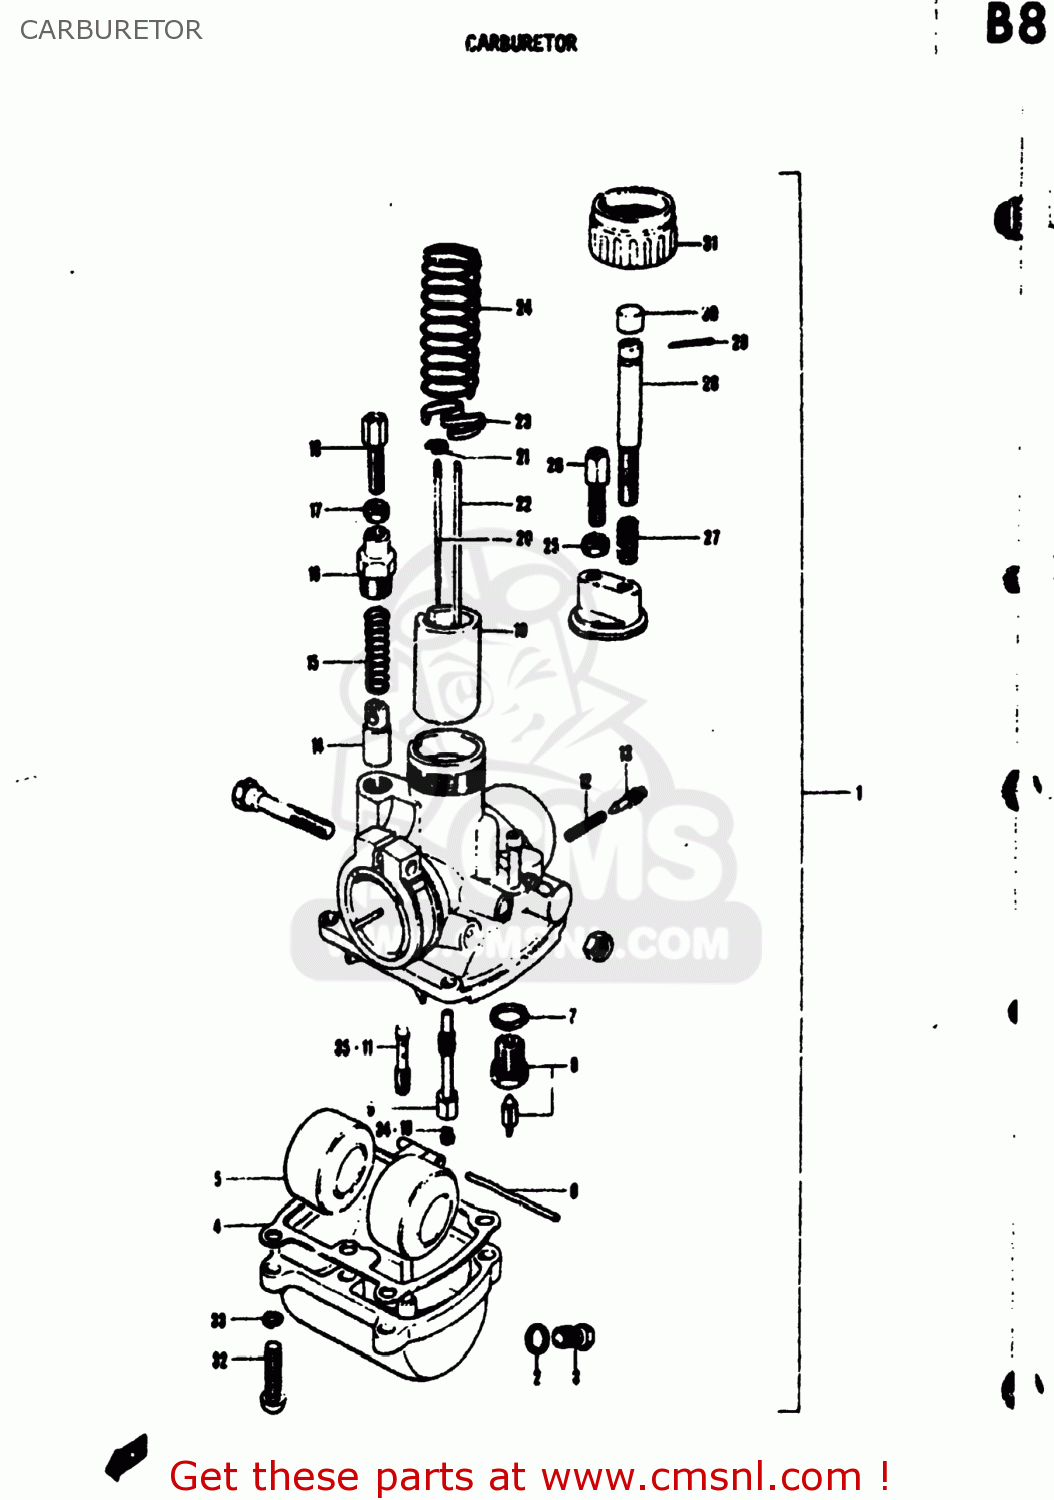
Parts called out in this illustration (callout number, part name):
1	CARBURETOR ASSEMBLY
2	GASKET,DRAIN,PLUG (NAS)
3	PLUG
4	GASKET,FLOAT CHAMBER (NAS)
5	FLOAT
6	PIN,FLOAT
7	GASKET,NEEDLE VALVE (NAS)
8	VALVE ASSEMBLY,NEEDLE
9	JET,NEEDLE
10	JET
11	JET
12	SPRING
13	SCREW,PILOT AIR
14	PLUNGER,STARTER
15	SPRING
16	CAP,STARTER PLUNGER
17	NUT
18	ADJUSTER,CABLE
19	VALVE,THROTTLE
20	NEEDLE,JET
21	CLIP,NEEDLE
22	ROD,THROTTLE VALVE STOP
23	PLATE,THROTTLE VALVE
24	SPRING,THROTTLE VALVE
25	NUT
26	ADJUSTER,CABLE
27	SPRING,THROTTLE STOP SCREW
28	SCREW,THROTTLE STOP
29	PIN 12X10
30	CAP,THROTTLE VALVE STOP SCREW
31	CAP,MIXING CHAMBER
32	SCREW
33	LOCK WASHER
34	JET
35	JET
